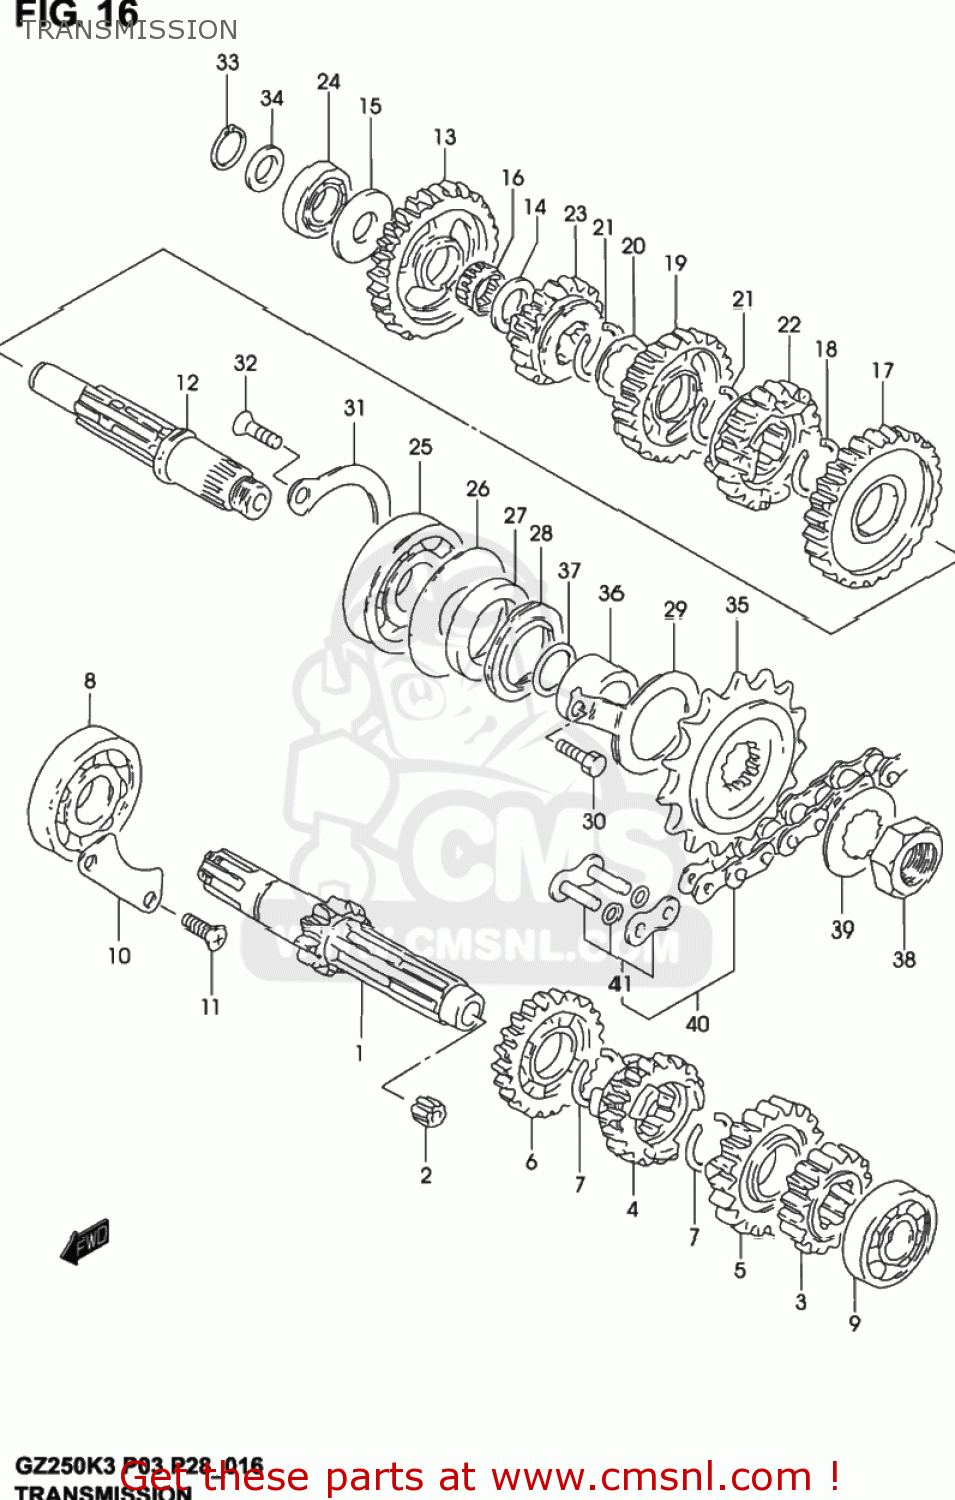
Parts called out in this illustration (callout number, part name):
1	SHAFT,COUNTER (NT:11)
2	BUSH
3	GEAR,2ND DRIVE(NT:16)
4	GEAR,3RD DRIVE(NT:19)
5	GEAR,4TH DRIVE(NT:20)
6	GEAR,5TH DRIVE(NT:22)
7	CIRCLIP
8	BEARING
9	BEARING(17X40X12)
10	RETAINER,CNTR SHAFT BEARING
11	SCREW
12	SHAFT,DRIVE
13	GEAR,1ST DRIVEN(NT:29)
14	SHIM(17X28X1)
15	WASHER
16	BEARING(17X21X9.8)
17	GEAR,2ND DRIVEN(NT:27)
18	CIRCLIP
19	GEAR,3RD DRIVEN(NT:24)
20	WASHER,LOCK
21	CIRCLIP
22	GEAR,4TH DRIVEN(NT:20)
23	GEAR,5TH DRIVEN(NT:18)
24	BEARING(17X36X12)
25	BEARING(22X56X16)
26	WASHER(35X55X1)
27	OIL SEAL (30X43X5)
28	SEAL,OIL(30X43X7)
29	RETAINER,DRIVE SHAFT OIL SEAL
30	BOLT
31	RETAINER,DRIVE SHAFT BEARING
32	SCREW
33	CIRCLIP,17MM
34	SHIM(17X24X1)
35	SPROCKET,ENGINE(NT:15)
36	SPACER
37	O RING(D:2.5,ID:21)
38	NUT
39	WASHER,LOCK
40	CHAIN(DID520VC5,110LE)
41	JOINT SET,CHAIN
